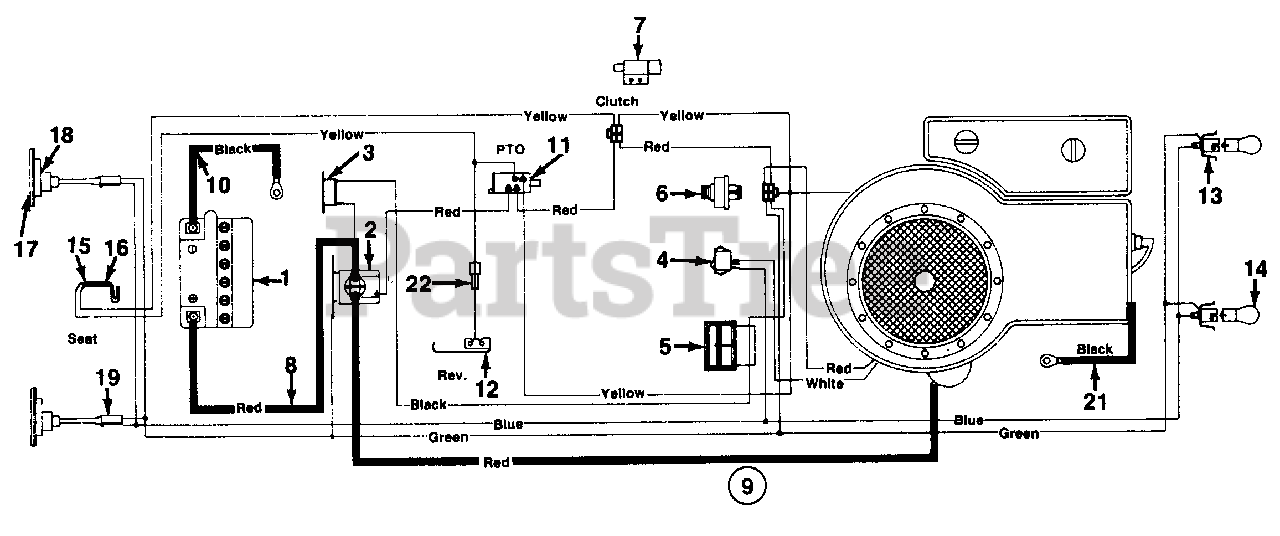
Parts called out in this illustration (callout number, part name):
1	Battery
2	Solenoid
3	Circuit Breaker
4	Light Switch
5	Ammeter
6	Ignition Switch
7	Safety Switch (Clutch)
8	Electric Wire 8" Lg.
9	Wire Harness
10	Ground Wire 11.5" Lg.
11	Safety Switch (Deck)
12	Safety Switch (Reverse)
13	Twist Lock Bulb Socket
14	Bulb
15	Safety Switch (Seat)
16	Safety Switch (Seat)
17	Taillight Bulb
18	Taillight
19	Taillight Harness
21	Ground Wire 7.5" Lg.
22	Extension Wire
